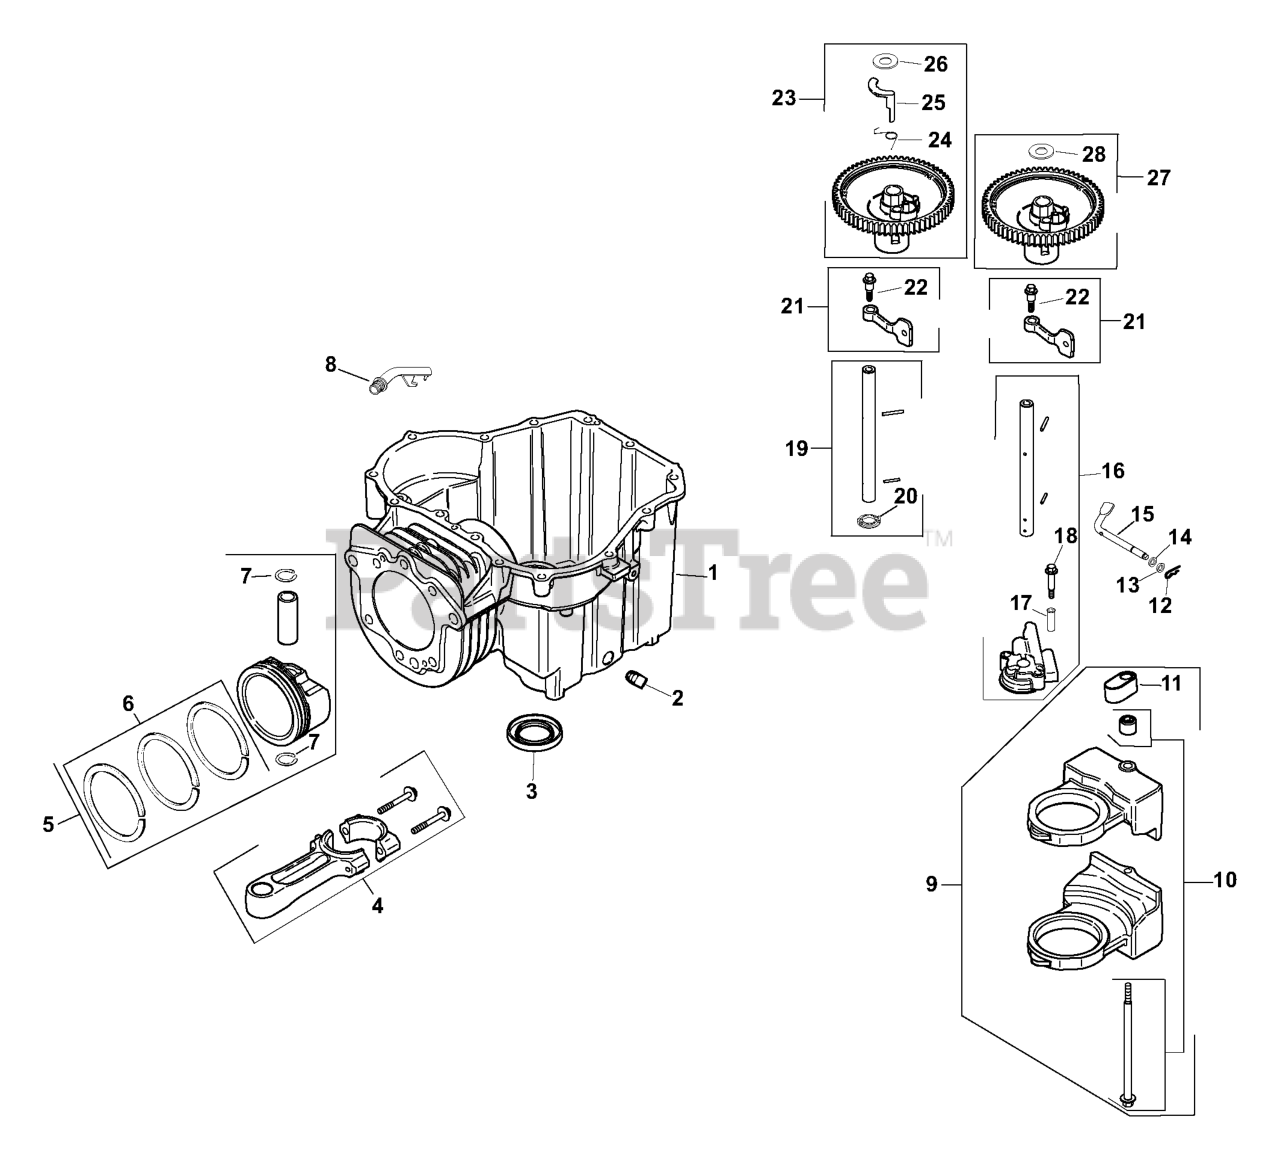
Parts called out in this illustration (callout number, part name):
1	Crankcase
2	Plug, Sq Hd Pipe 3/8"
3	Seal, Oil
4	Rod, Connecting
5	Kit, Piston W/ring Set (94mm)
6	Ring Set (94 Mm)
7	Retainer, Piston Pin
8	Tube, Drainback
9	Kit, Balance Weight
10	Kit,locating Pin
11	Shoe, Guide
12	Clip, Hitch Pin
13	Washer, Flat 6 mm
14	Washer, Flat 1/4"
15	Shaft, Governor Cross
16	Kit, Oil Pump Assembly
17	Spacer, Oil Pump Screw
18	Screw, Oil Pump
19	Kit, Camshaft Center Exhaust Assembly
20	Washer, Thrust
21	Kit, Cam Lever Assembly
22	Screw, Shd Thd FRM M6x1x26
23	Kit, Camshaft Assembly
24	Spring, ACR
25	Weight, ACR
26	Washer, Thrust -ACR
27	Kit, Camshaft Assembly
28	Washer, Thrust -ACR
